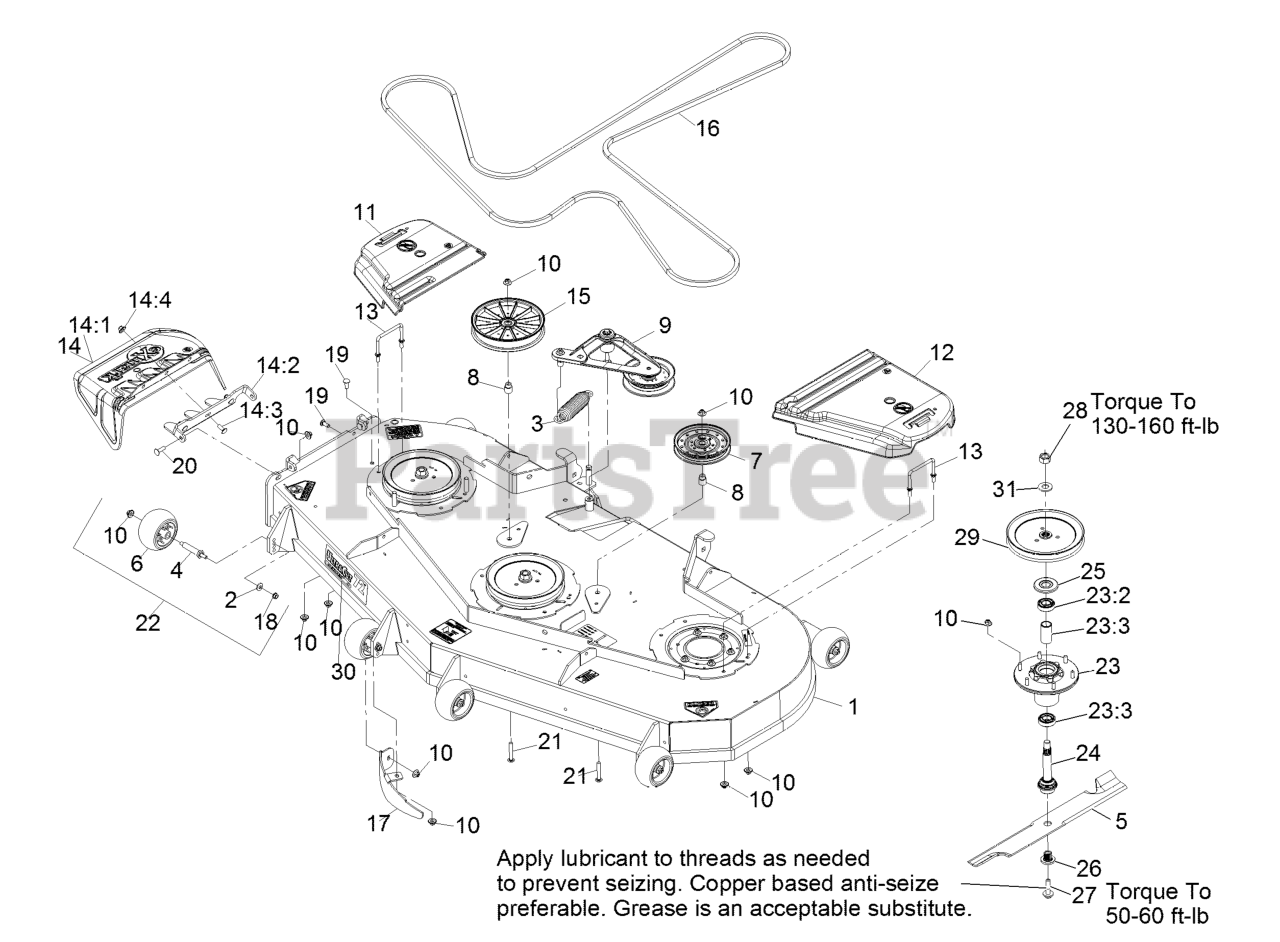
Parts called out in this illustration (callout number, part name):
1	ASM,DECK W/DECALS 724
2	WASHER-BELLEVILLE
3	SPRING-EXTENSION
6	ROLLER-SCALP, ANTI
8	BUSHING-IDLER
9	DECK IDLER ASM
10	Nut-Nyloc 3/8-16 Flg
11	COVER-BELT, RH
12	COVER-BELT, LH
13	WIREFORM-COVER
14	ASM,DISCHARGE CHUTE
14:1	CHUTE,DISCHARGE
14:2	BRACKET,DISCHARGE CHUTE
14:3	SCREW-CARR
14:4	Nut-Nyloc 3/8-16 Flg
15	PULLEY,IDLER 8"FLAT
16	BELT-V
17	BAFFLE-DOGLEG, LZ72
18	NUT-HHF, WHIZ
19	SCREW-CARR
20	Bolt-Carriage 3/8-16 X 1 1/4
21	SCREW-CARR
23	ASM-CUTTER HSG WITH BEARINGS
23:2	BEARING-BALL
23:3	SPACER-BEARING
24	ASM-SPINDLE AND SEAL
25	GUARD,BEARING TOP .989
26	BUSHING,SPLINED
27	SCREW,SEMS 1/2-20 X 2.19
28	NUT-HEX
29	SHEAVE,BLADE DRIVE 8.74
30	DECAL,ULTRACUT 72 SERIES
